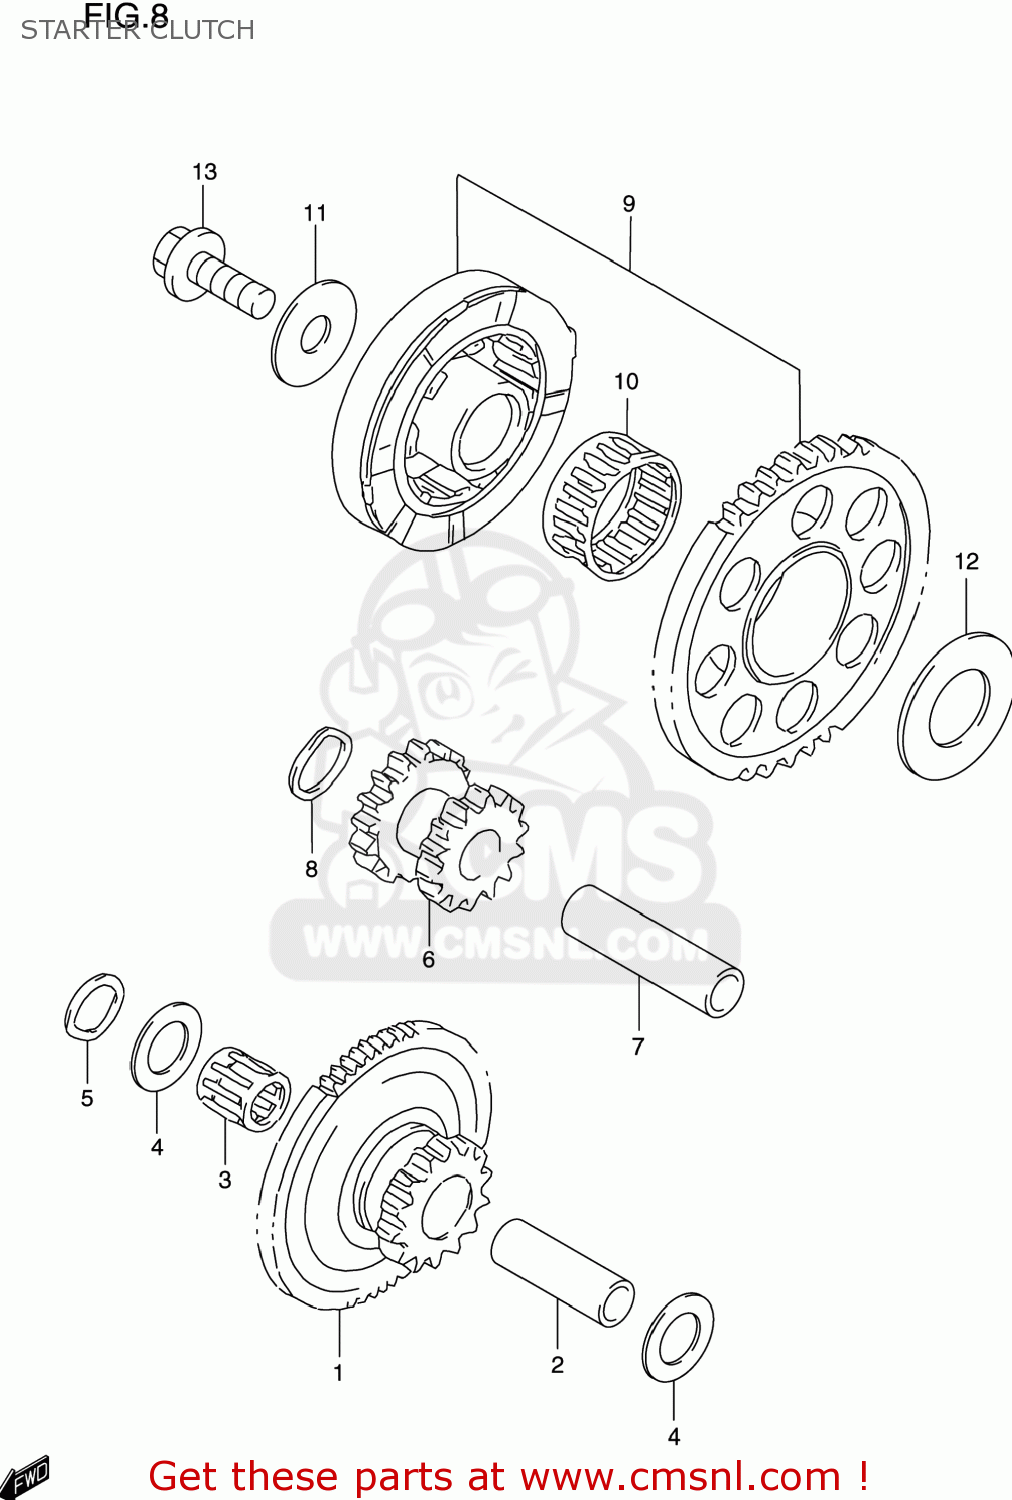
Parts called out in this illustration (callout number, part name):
1	GEAR,STARTER IDLE NO.1
2	PIN,PISTON
3	BEARING(12X16X16)
4	WASHER
5	WASHER
6	GEAR,STARTER IDLE NO.2 (N
7	PIN ,PISTON
8	WASHER
9	CLUTCH SET,STARTER
10	BEARING(28X34X16.8)
11	WASHER
12	WASHER
13	BOLT(10X23)
